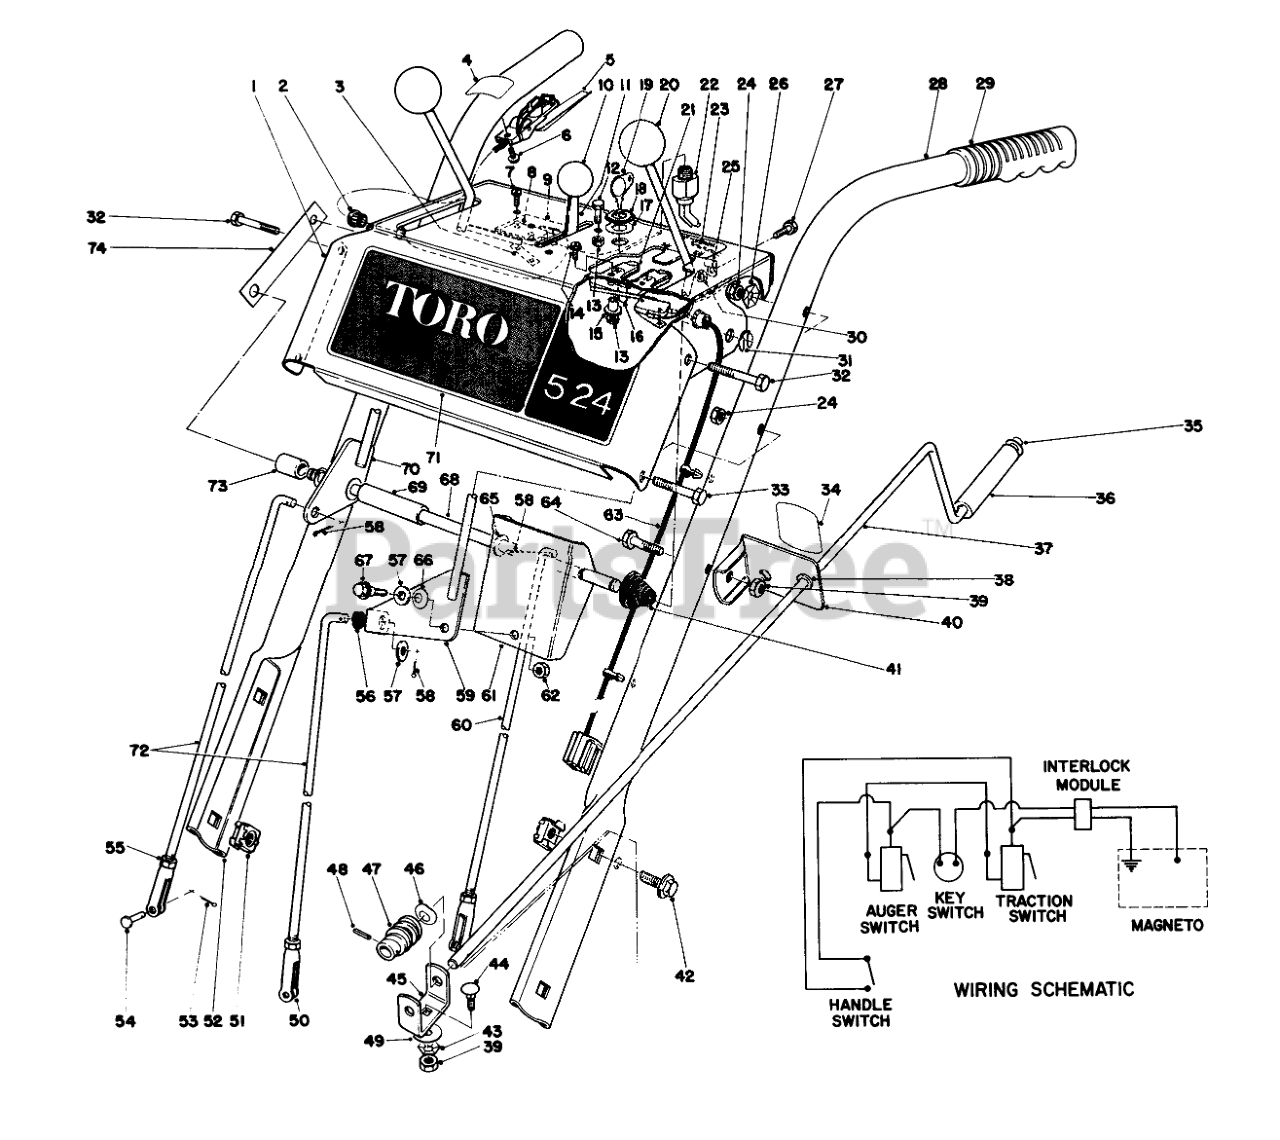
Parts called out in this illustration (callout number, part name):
1	ESCUTCHEON PLT B
2	BUSHING NYLON
3	NUT-SPEED
4	INTERLOCK DECAL
5	INTERLOCK HDLE SWITCH
6	SCREW
7	SCREW-SPH
8	SWITCH-MICRO
9	SWITCH MTG PAD
10	CONTROL KNOB
11	THROTTLE CONTROL
12	HEX HEAD SEMS 10-24X1/2
13	Nut
14	SCREW-SRH
15	INTERLOCK SPACER
16	INTERLOCK SPRING
17	WASHER-TOOTH, INTERNAL
18	NUT-HH
19	Key
21	Slide Interlock
22	Key Switch
23	INSTR DECAL
24	NUT-LOCK, CONE
25	CLAMP-NYLON
26	NUT-HHF, WHIZ
28	LEFT HANDLE
29	Grip Handle
30	NUT-KEPS
31	RING-CLIP
32	SCREW-HH
33	SCREW-HH
34	CHUTE DECAL
35	RETAINER-PUSH ON
36	GRIP-CONTROL, CHUTE
37	CHUTE CONTROL ROD
38	Bushing
39	NUT-LOCK, NI
40	Chute Control Rod Mounting (Incl. Ref #34 & 38)
41	CONICAL SPRING
42	SCREW-HHF
43	WASHER-LOCK
44	BOLT-CARR
45	WORM BRACKET
46	WASHER-SPRING
47	GEAR-WORM, CHUTE
48	PIN-SPRING
49	WASHER
50	CLEVIS
51	Retained Nut
52	HANDLE RIGHT
53	PIN-COTTER
54	PIN-CLEVIS
55	NUT-HJ
56	GROMMET-RUBBER
57	WASHER-FLAT
58	PIN-COTTER
59	SHIFT LEVER WA
60	TRACTION CONTROL ROD
61	SHIFT BRACKET
62	NUT-LOCK, CONE
63	WIRE HARNESS INTERLOC
64	SCREW-HH
65	WASHER-FLAT
66	7/16 SPRING WASHER
67	SHOULDER SCREW
68	PIVOT ROD
69	SHIFT LEVER SPACER
70	LEVER WA
71	ESCUTCHEON DECAL
72	SPEED SELECTOR ROD
73	AUGER LEVER SPACER
74	ESCUTCHEON SUPT STRAP
